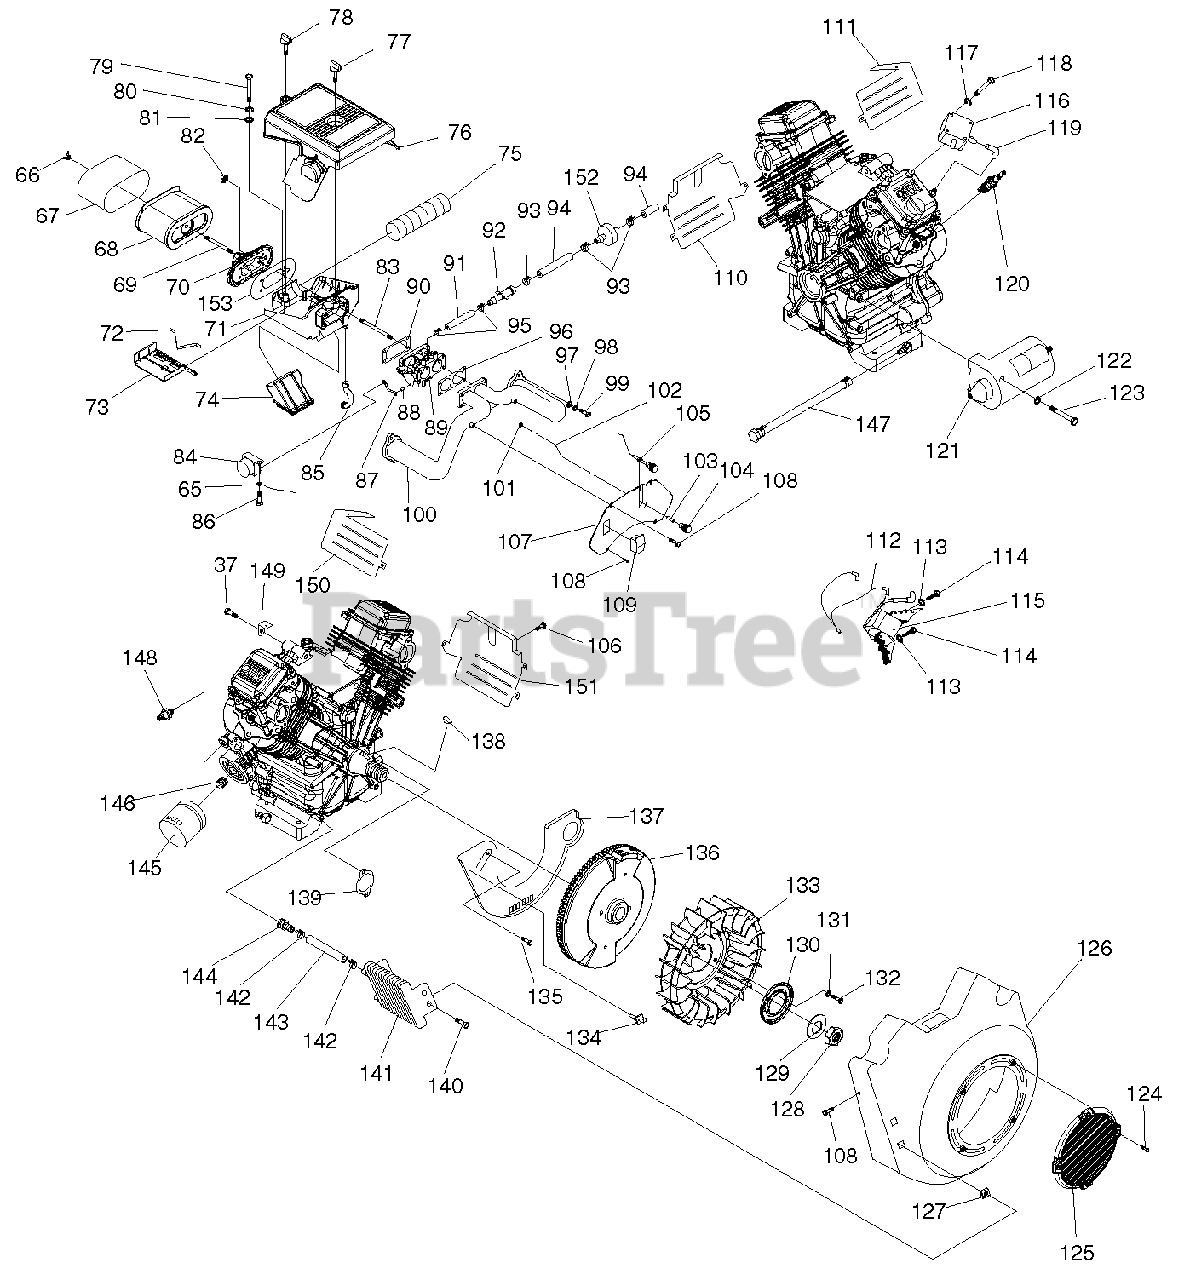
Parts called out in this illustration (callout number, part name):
65	ASSEMBLY WIRE
66	WINGNUT, AIRBOX
67	PRECLEANER, AIR
68	ELEMENT, AIR CLEANER
69	STUD M6-1.0 X 73
70	ADAPTOR, SPIT BACK
71	BASE, AIRBOX
72	SPRING, WINTER/SUMMER VALVE
73	VALVE, SUMMER / WINTER
74	SNORKEL, AIR INTAKE
75	TUBE, HEAT RISER 50.8 I.D.
76	COVER, AIRBOX
77	KNOB, AIRBOX 17mm
78	KNOB, AIRBOX 95MM
79	SCREW HHC M6-1.0 X 35
80	WASHER LOCK M6-1/4
81	WASHER FLAT 1/4
82	NUT LOCK FLANGE M6-1.0
83	STUD, METRIC
84	CONTROLLER ASSEMBLY
85	HOSE, BREATHER
86	SCREW HHTT M5-0.8 X 10
87	ROD,GOV. STEP MOTOR-CARBURETOR
88	SPACER, ROD-THROTTLE
89	CARBURETOR
90	GASKET,CARB TO SPACER
91	HOSE 3/16ID
92	ADAPTER,HOSE MENDER 1/4"X3/16"
93	CLAMP HOSE BAND 1/4
94	HOSE 1/4 ID
95	CLAMP HOSE BAND 3/16
96	GASKET, MANIFOLD TO CARBURETOR
97	WASHER FLAT M8
98	WASHER LOCK M8
99	SCREW SHC M8-1.25 X 30
100	MANIFOLD, INTAKE
101	NUT HEX M3-0.5
102	ROD, SUMMER / WINTER VALVE
103	SLEEVE, INSERT WINTER/ SUMMER KNOB
104	KNOB, CONTROL SUMMER/ WINTER
105	CHOKE ASSEMBLY
106	SCREW TAPTITE M5-0.8 X 8 BP
107	PANEL, CONTROL FACE PLATE
108	SCREW TAPTITE M6-1.0X8 YELLOW CHROME
109	SWITCH ROCKER
110	WRAPPER, LOWER CYLINDER 2
111	WRAPPER, UPPER CYLINDER 2
112	ASSEMBLY, GROUND WIRE
113	WASHER LOCK M6-1/4
114	SCREW TAPTITE M6-1.0 X 25 BP
115	ASSEMBLY, IGNITION COIL
116	PUMP, IMPULSE
117	WASHER LOCK M4
118	SCREW PPHM M4-0.7 X 40
119	ELBOW, RUBBER 90 DEG.
120	SPARKPLUG
121	STARTER
122	WASHER LOCK M8-5/16
123	SCREW HHC M8-1.25 X 85 G8.8
124	SCREW, HI-LO SELF TAP #10- 16X1.25
125	ROTATING SCREEN
126	HOUSING, BLOWER GASOLINE COOLER
127	NUT, GROMMET 1/4 PLUG
128	NUT,HEX M24
129	WASHER, M24
130	PLATE, FAN
131	WASHER SHAKEPROOF INT M8 SS
132	SCREW HHC M8-1.25 X 12 G8.8
133	FAN, NYLON
134	INSULATOR ASSEMBLY IGNITION
135	SCREW TAPTITE M6-1X10 YELLOW CHROME
136	FLYWHEEL ASSEMBLY
137	PLATE, BACKING GT990 WITH OIL COOL
138	KEY, WOODRFF 4 X 19D
139	GASKET, MANIFOLD / PORT
140	PLASTITE,1/4-15 X 3/4
141	COOLER, OIL
142	CLAMP HOSE #5.5 .62 - .62
143	HOSE, 3/8" I.D. X 6" LONG
144	BARBED STR 1/4NPT X 3/8 WITH VIBRA SEAL
145	FILTER, OIL D 69 X 64 LONG
146	NIPPLE, 3/4"-16 UNF
147	ASSEMBLY, OIL DRAIN HOSE
148	SWITCH, OIL PRESS
149	BRACKET, AIRBOX SUPPORT
150	WRAPPER, UPPER CYLINDER 1
151	WRAPPER, LOWER CYLINDER 1
152	FILTER, FUEL
153	GASKET, SPITBACK
